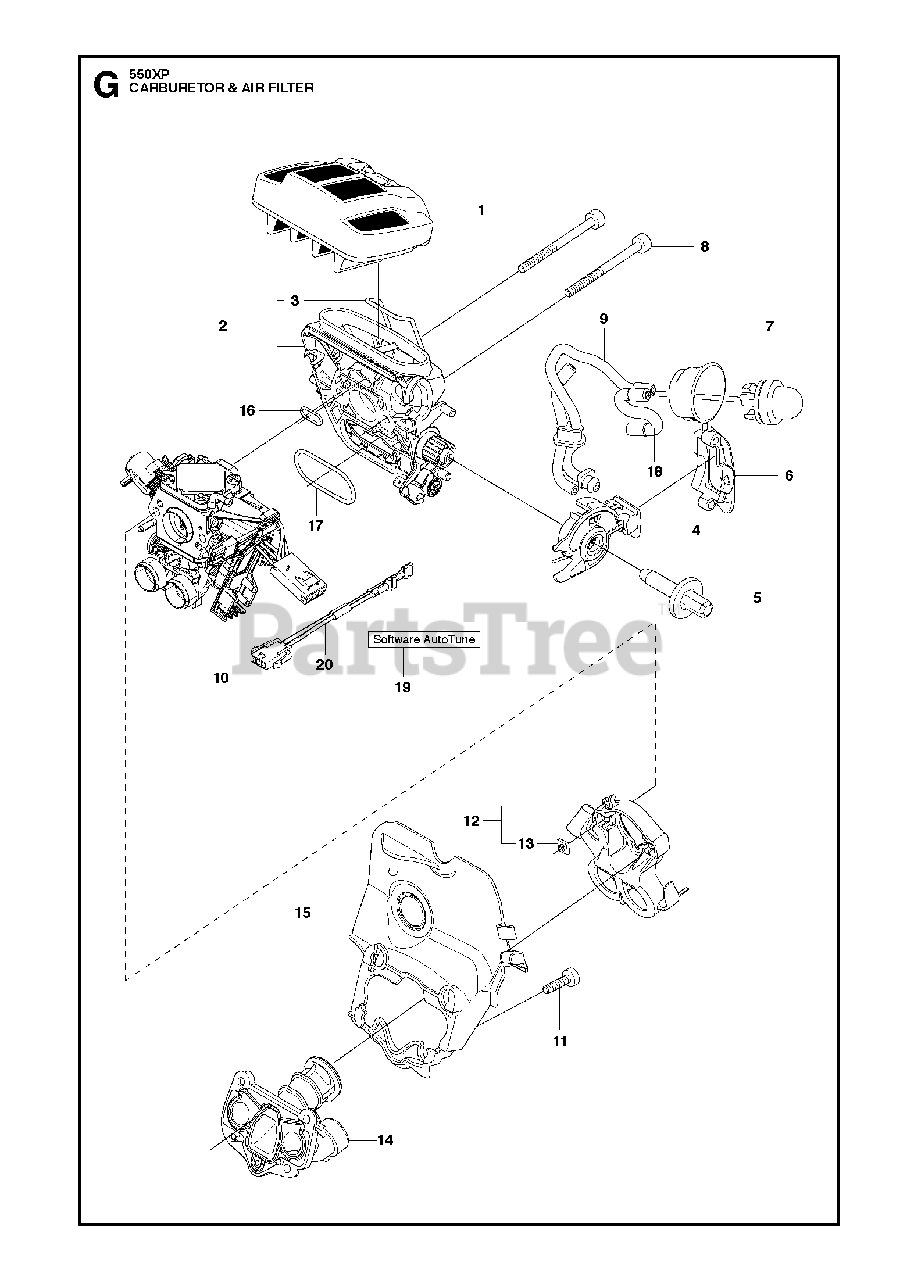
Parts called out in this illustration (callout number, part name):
1	AIR FILTER ASSY
2	FILTER HOLDER ASSY
3	SHACKLE
4	CHOKE CONTROL ASSY
7	AIR PURGE BUBBLE
9	FUEL HOSE
10	RP CARBURETTOR
11	SCREW IHSCM
12	FLANGE
13	NUT
14	INLET PIPE ASSY
15	INTERMEDIATE WALL
19	Husqvarna TBD
20	WIRING ASSY
